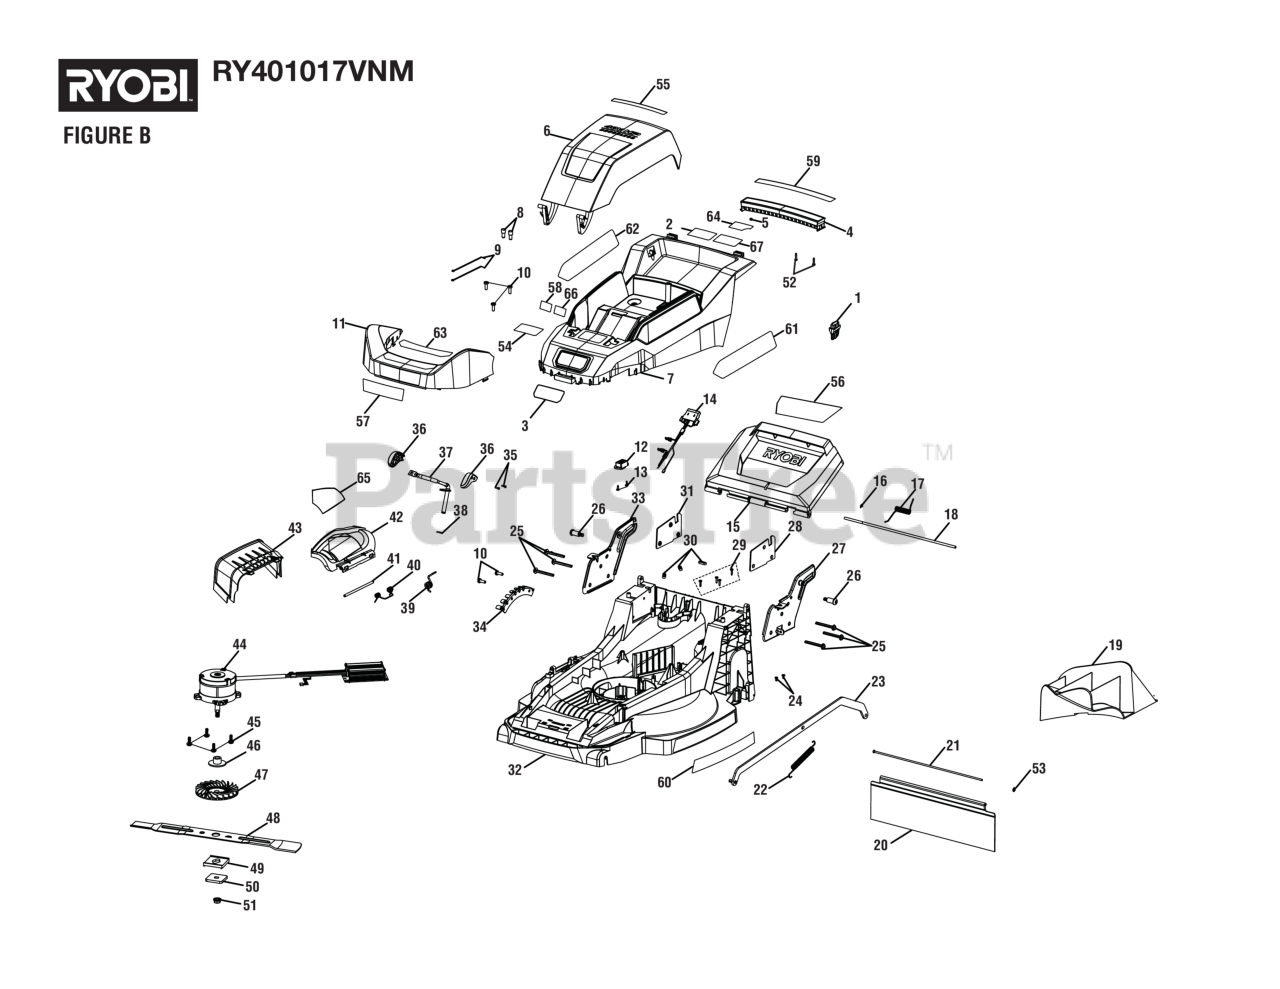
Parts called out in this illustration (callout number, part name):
1	Start Key
2	Battery Wet Conditions Label
3	Logo Label
4	Carry Handle
5	Door Magnet
6	Battery Cover
7	Top Housing
8	Close-End Connector
9	NYLON CABLE TIE
10	Screw (1/4-15 x 3/4 in., T30 Torx Pan Hd.)
11	Front Fender
12	Key Holder
13	Screw (M4.2 x 12 mm, T20 Torx Pan Hd.)
14	Inner Wire Without Terminal
15	Rear Door
17	Rear Door Torsion Spring
18	Rear Door Shaft
19	Mulching Plug
20	Trailing Sheet
21	Trailing Sheet Rod
22	Retention Spring
23	Connecting Bar
24	Screw (M4 x 8 mm, T25 Torx Pan Hd. T.F.)
25	Screw (M6 x 64 mm, T30 Torx Pan Hd.)
26	Screw w/Shoulder (M8 x 35.7 mm, T45 Torx Pan Hd.)
27	Handle Bracket (Left)
28	Handle Bracket Nut Plate
29	Screw (M4 x 16 mm, T20 Torx Pan Hd.).
30	Wire Press Plate
31	Right Handle Bracket Nut
32	Deck
33	Right Handle Bracket
34	Height Adjustment Plate
35	Screw (M3 x 12 mm, Pan Hd.)
36	Height Adjustment Knob Assembly
37	Height Adjustment Rod
39	Height Adjustmen Rod Torsion Spring
40	Side Discharge Cover Torsion Spring
41	Side Discharge Shaft Cover
42	Side Discharge
43	Side Discharge Chute
44	Push Mower Controller Assembly
45	Screw (M6 x 1 mm, T30 Torx Pan Hd.)
46	Motor Shaft Bushing
47	Motor Fan Blade Adapter
48	20 in. Blade
49	Plastic Blade Spacer
50	Blade Spacer Metal Plate
51	Blade Nut (M10 x 1.25, Hex Flange Hd.)
52	Screw (M4 x 18 mm, T20 Torx Pan Hd.)
53	Retaining Ring
54	Data Label (TUV)
54	Data Label (UL)
55	Icon Label
56	Danger Label (Bagger Door)
57	3-In-1 Front Label
58	Battery Storage Label
59	Carry Handle Accent Label
60	Deck 20in Side Label
61	Brushless Logo Label
62	Brushless Logo Label
63	Push Front Bumper Label
64	Qr Code Label
65	Danger Label (No Hands/Feet)
66	Start Key Label (Spanish)
67	Start Key Label (French)
